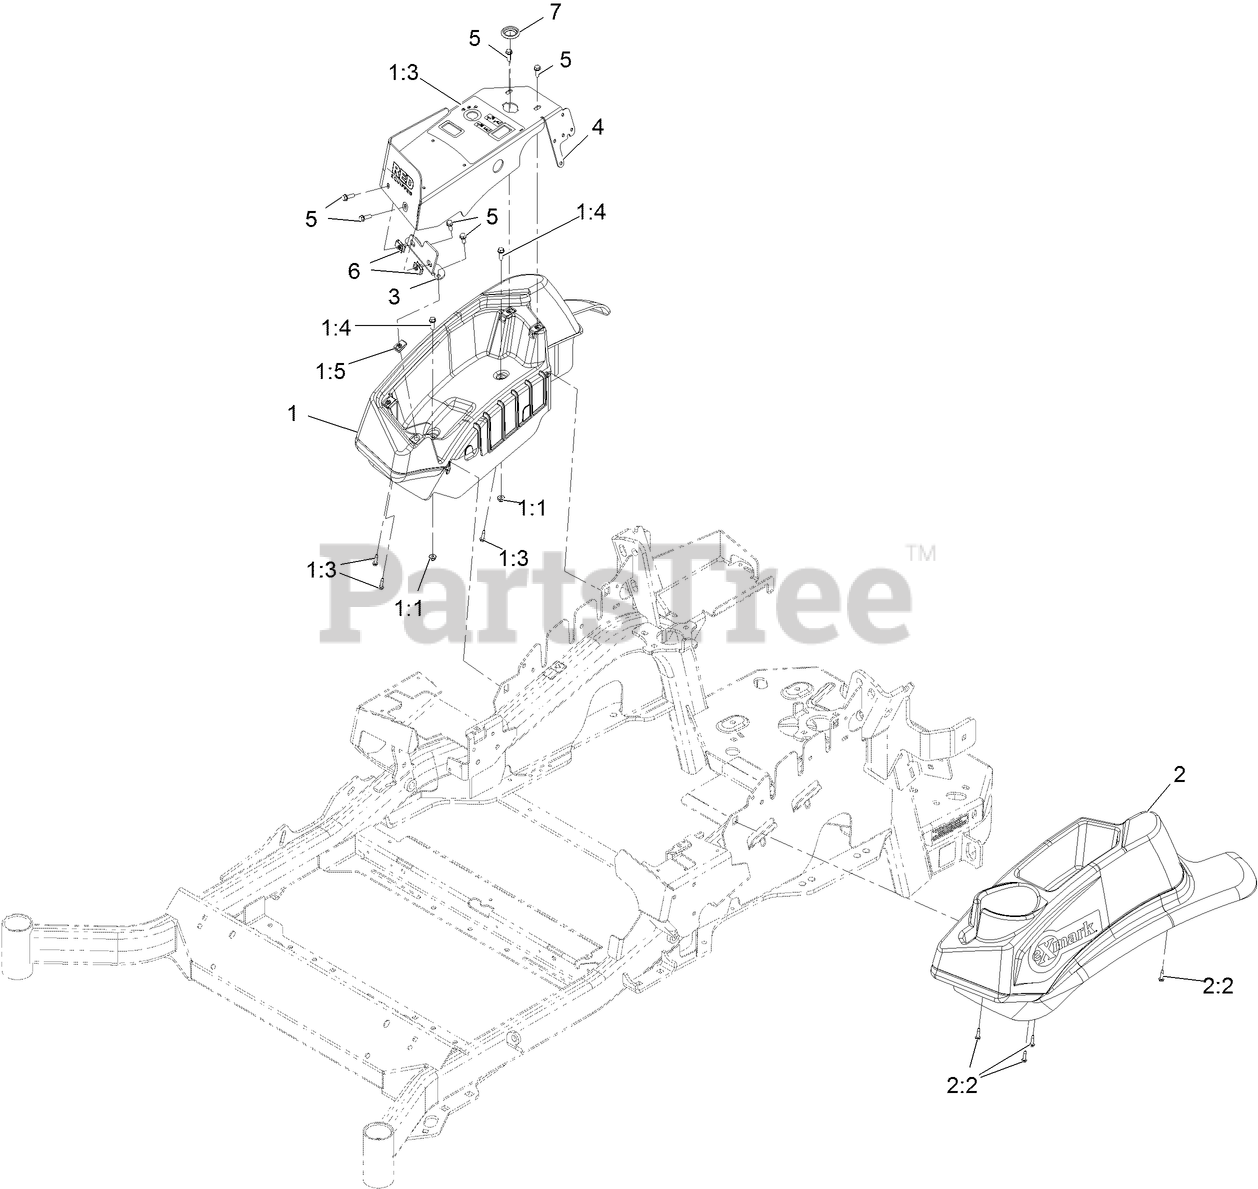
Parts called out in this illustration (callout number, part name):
1	CONSOLE,RH NARROW ASM
1:3	SCREW,THD FORM,HWH
1:4	SCREW-HWH
2	CONSOLE.LH NARROW ASM
2:2	SCREW,THD FORM,HWH
3	BRACKET-CONSOLE
4	COVER-PANEL ASM W/DECALS
5	SCREW-HWH
7	PLUG-PLASTIC
